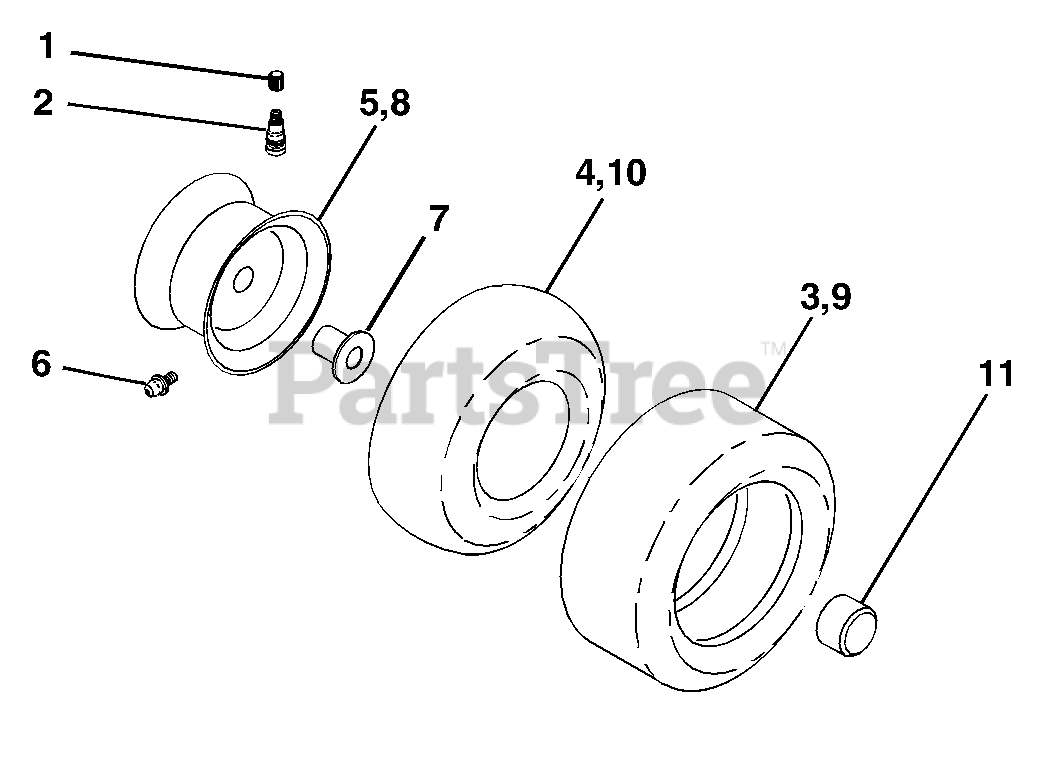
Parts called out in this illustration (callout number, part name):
1	Cap Valve Tire
2	Stem Valve
3	Tire F T 15 x 6 0 - 6 Service
4	Tube Front (Service Item Only)
5	Rim Asm 6"front Service
6	Fitting Grease (Front Wheel Only)
7	Bearing Flange (Front Wheel Only)
8	Rim Asm 8"rear Service
9	Tire R T 20 x 10 -8 C Service
10	Tube Rear (Service Item Only)
11	Cap Axle 1 50 x 1 00
